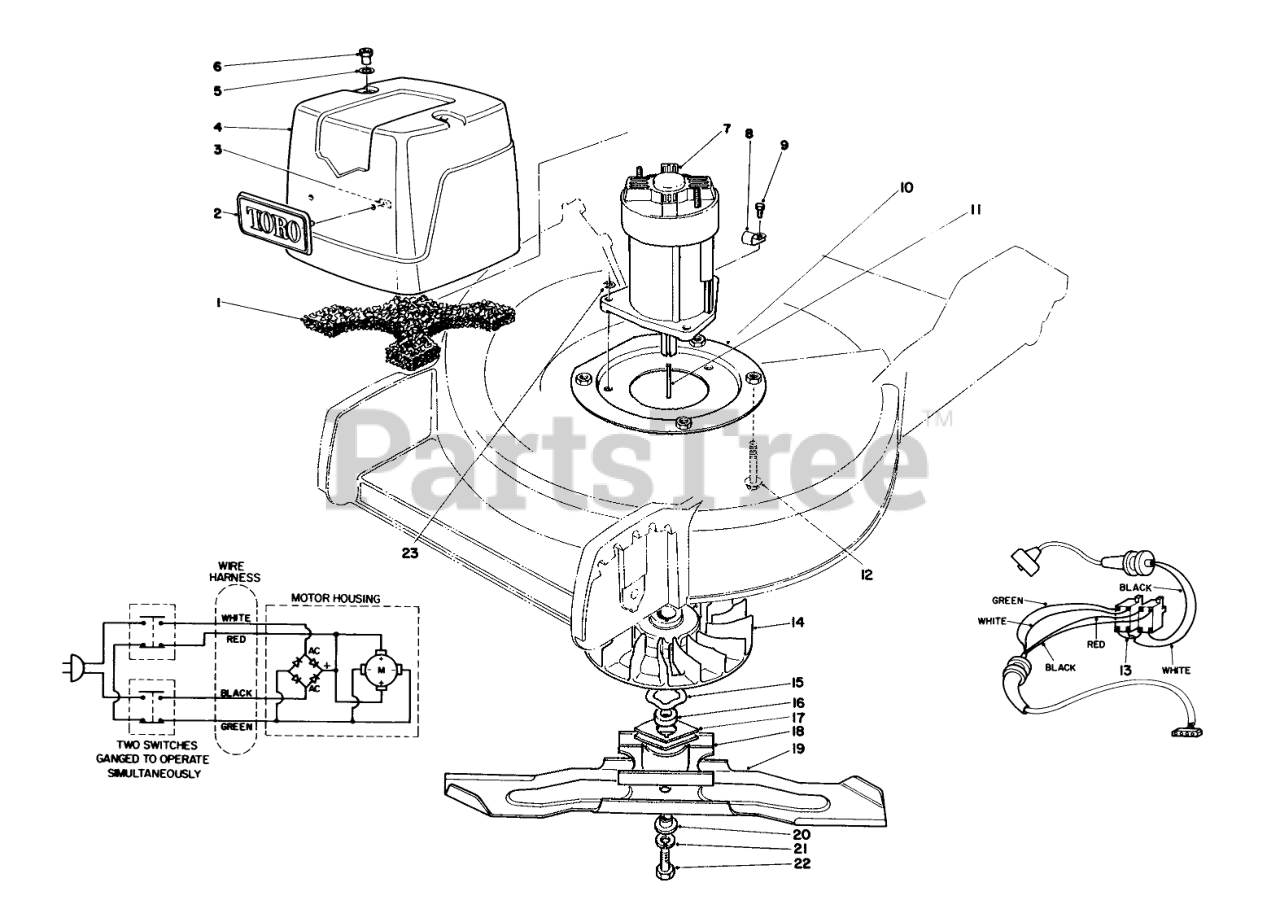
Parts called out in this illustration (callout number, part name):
1	FILTER F/W
2	TORO LOGO PLT
3	Receiver-Stud
4	Shroud-Motor
5	WASHER F/W
6	NUT F/W
7	Motor-Electric
8	CLIP-CLOSED, INSULATED
9	SCREW-HH
10	MOTOR MOUNT ASM WA
11	1/8 X 1/40 SQUARE KEY
12	SCREW-HHF
13	BRAKE WIRE
14	FAN F/W
15	WAVE WASHER
16	BLADE RETAINER SPACER
17	FAN DRIVER
18	BLADE RETAINER WA
19	Blade
20	BLADE SPACER
21	WASHER-LOCK/SP
22	SCREW-HH
23	WASHER-LOCK/EXT
